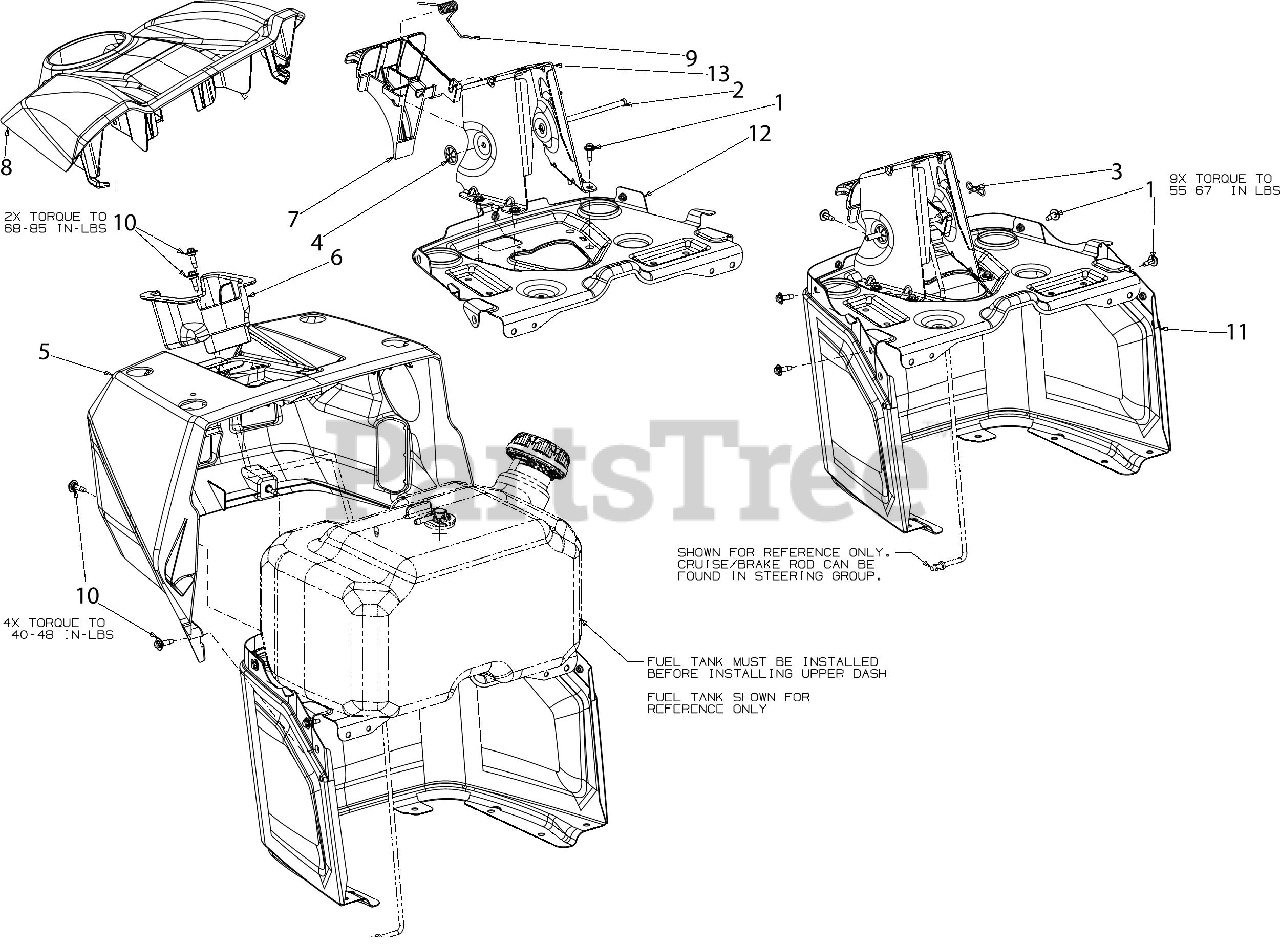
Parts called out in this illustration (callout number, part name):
1	SCREW M6-1 x .625
2	HINGE PIN .25 x 4.50
3	BOW TIE COTTER PIN 1/4-5/16
4	PUSH ON NUT
5	UPPER DASH
6	STEERING SHAFT BEARING
7	CRUISE/BRAKE DASH LEVER
8	UPPER DASH CAP
9	TORSION SPRING .330 ID
10	SHOULDER SCREW M6-1 .368 X.115
11	LOWER DASH
12	DASH/FUEL TANK PLATE
13	STEERING MOUNT BRACKET
